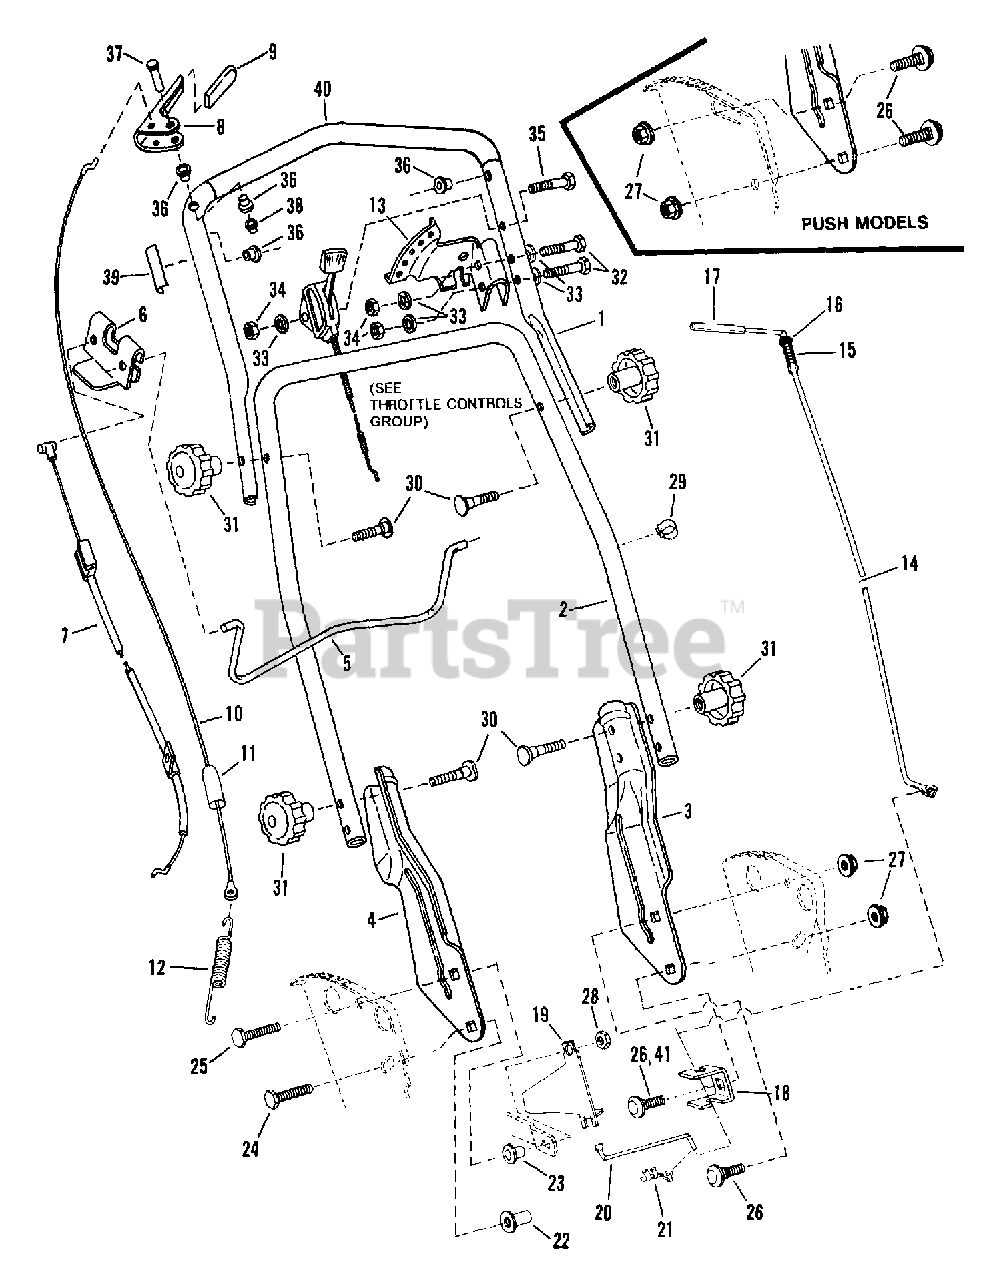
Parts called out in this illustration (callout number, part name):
1	HANDLE, Upper
2	HANDLE, Middle
3	HANDLE, Lower Left Hand
4	HANDLE, Lower Right Hand
5	CONTROL, Blade
6	CLIP, Blade Control
7	CABLE, Blade Control, 47.94" Overall length
7	CABLE, Blade Control, 63.87" Overall length
7	CABLE, Blade Control, 52.65" Overall length
7	CABLE, Blade Control, 46.3" Overall lenght
7	CABLE, Blade Control, 56.93" Overall length
7	CABLE, Blade Control, 63.42" Overall length
7	CABLE, Blade Control, 57.0" Overall length
7	CABLE, Blade Control, 47.95" Overall length
8	HANDLE, Wheel Drive
9	GRIP, Wheel Drive Handle
10	CABLE, Clutch Pull (Z-BEND)
11	COVER, Vinyl
12	SPRING, Clutch
13	SECTOR, Speed
14	LEVER, Speed Control
15	SPRING, Speed Control
16	WASHER, 3/8" Flat
17	GRIP, Speed Control Handle
18	ANCHOR, Speed Control
19	GUIDE, Lower V-Belt
20	ROD, Transfer
21	CLIP, Transfer Rod
22	TEE-NUT, 5/16-18
23	BUSHING, Differential
24	BOLT, 5/16-18 x 3/4 Flange Lock
25	CAPSCREW, 5/16-24 x 1
26	BOLT, 5/16-18 x 5/8 Carriage
27	NUT,5/16-18 Hex Flange Lock
28	NUT, 5/16-24 Center Lock
29	CLIP Cable/Wiring
30	SCREW, 1/4-20 x 1-7/8 Curved Head
31	KNOB, 5/16-18
32	CAPSCREW, 1/4-28 x 1-3/8
33	LOCKWASHER, 1/4 Internal Tooth
34	NUT, 1/4-20 Hex
35	CAPSCREW, 1/4-28 x 1-3/4
36	BUSHING
37	PIN, Clutch Handle
38	PUSH-NUT (for handle pin)
39	DECAL, Blade Control
40	GRIP, Foam 18"
40	GRIP, Foam 13.5"
41	BOLT, 5/16-18 x 5/8" Carriage
